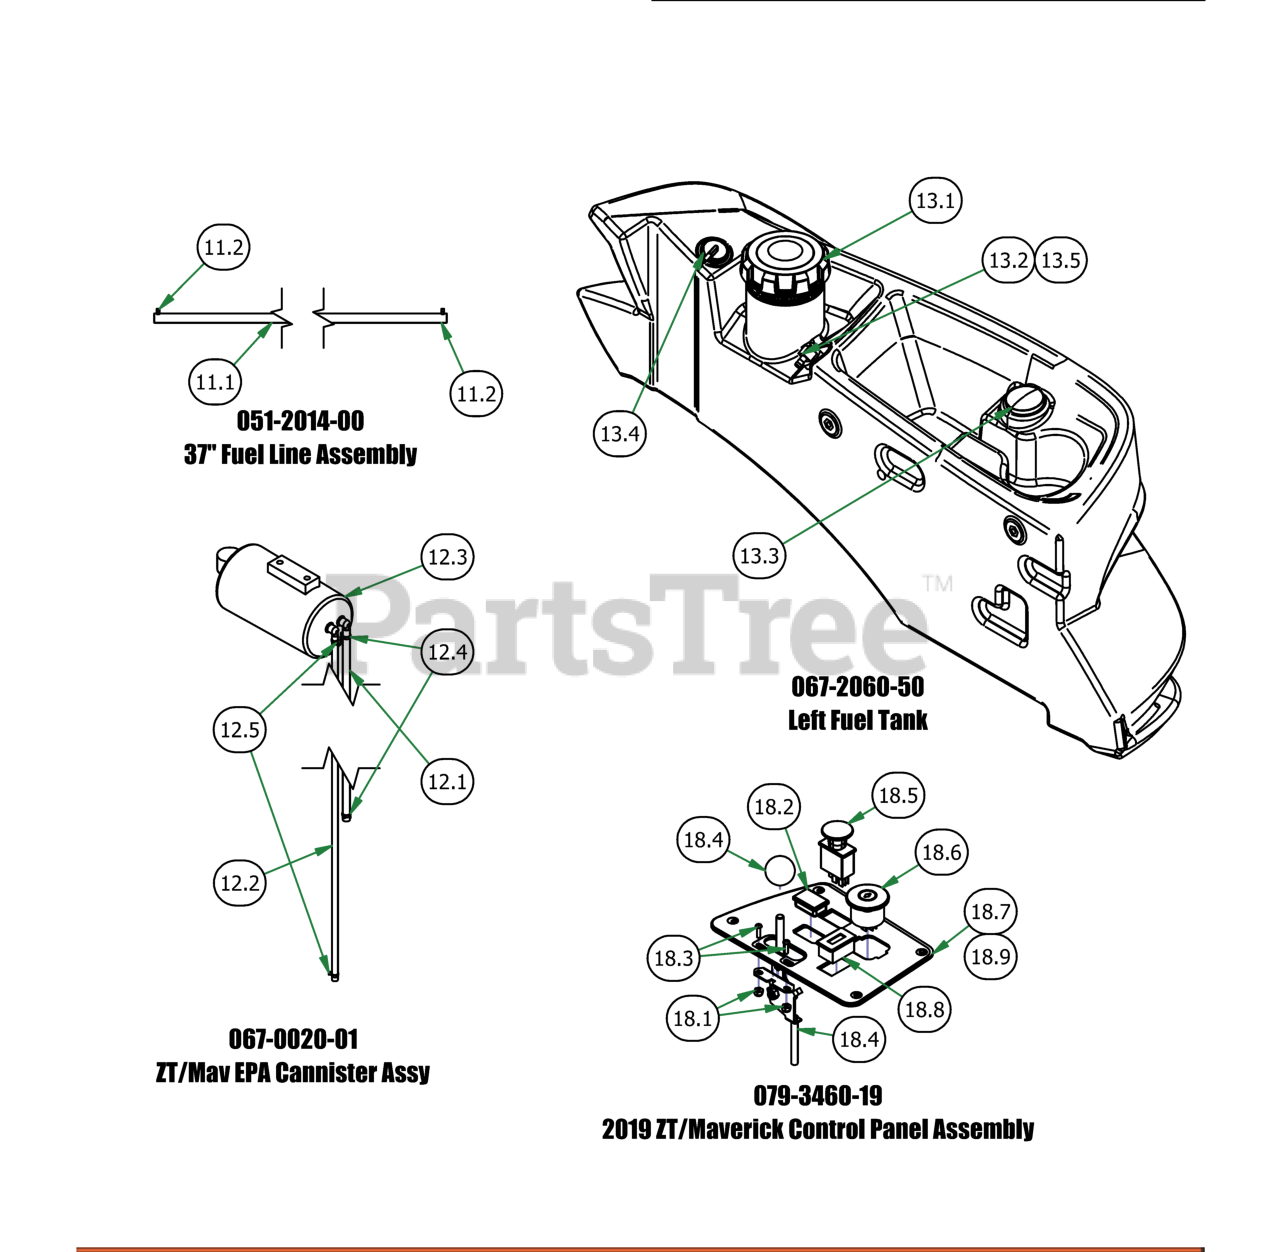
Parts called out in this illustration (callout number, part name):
11.1	37" 1/4 Fuel Line
11.2	1/4 Fuel Hose Clamp
12.1	1/4" Vinyl Tubing, 46" Long
12.2	3/16" Vinyl Tubing, 55" Long
12.3	Carbon Canister
12.4	3/16 Vinyl Clamp
12.5	3/16" Vinyl Hose Clamp
13.3	Fuel Gauge w/Grommet
13.4	Rollover Valve W/Grommet
13.5	Pick-Up Grommet
18.1	10-24 Nylon Insert Locknut Zinc Orange Nylon
18.2	Light Plug
18.3	10-24 X 5/8 BS Button Head Bold
18.4	Throttle Lever Assembly
18.5	PTO Engager
18.6	Ignition Switch
18.7	Control Panel
18.8	Tachometer
18.9	2018 MZ/Magnum/ZT/Maverick Control Panel Decal
